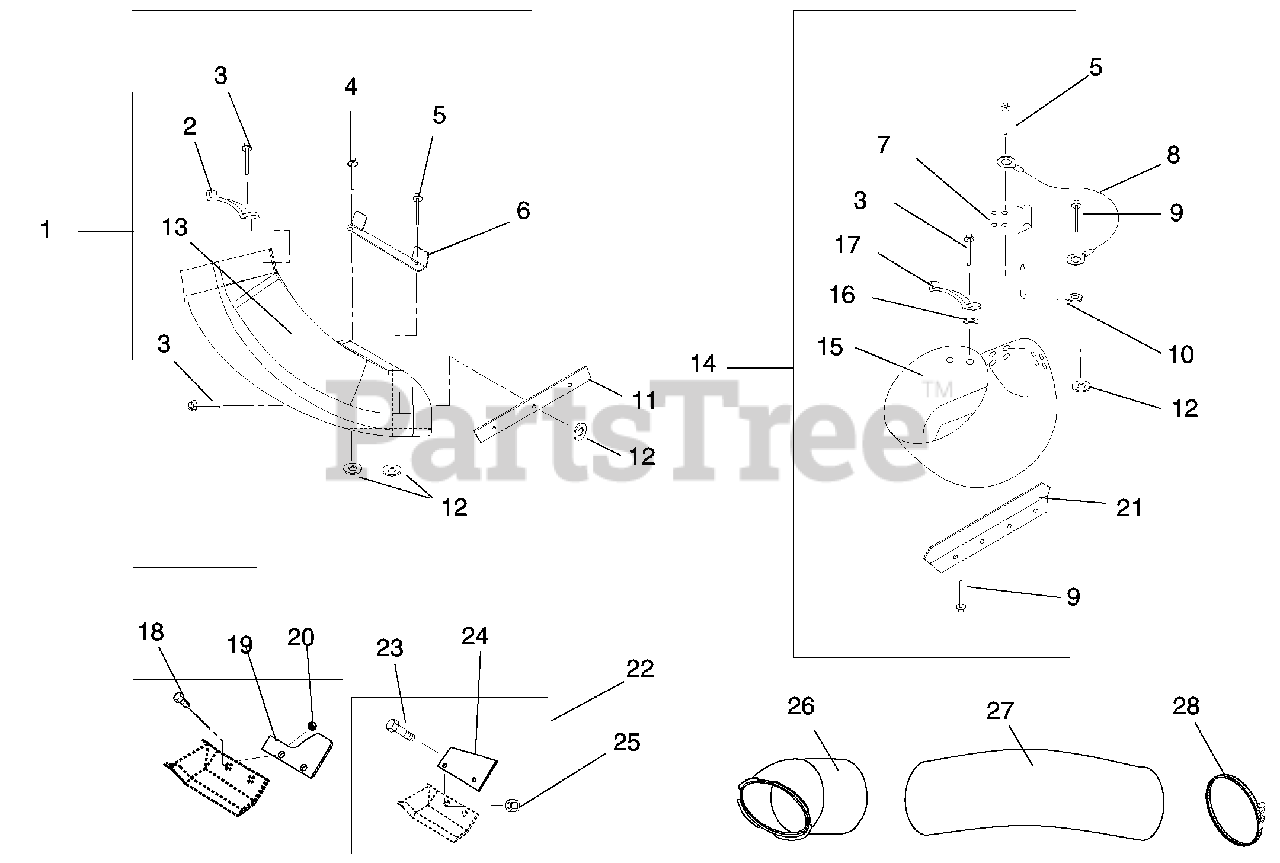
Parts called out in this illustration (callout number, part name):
1	BOOT, 28"&32" DECK BAGGER
2	TUBE RETAINER
3	RVT-POP.187X.527 DOME ST
4	RVT-POP.187X.277 DOME ST
5	RVT-POP .187X.402 DOME ST
6	BRKT, BAGGER BOOT MOUNT
7	BOOT BRACKET
8	LANYARD
9	RVT-TBLR .187X.375 ST-AL PL
10	PULL PIN
11	SKIRT, RUBBER
12	@WSHR-FL-STL.219X.50X.049 YWZC
13	28"/32" BOOT ASSY
14	MOWER BOOT ASSY- 40"
15	PAN BOOT ASSEMBLY
16	@WSHR-FL-STL.219X.50X.049 YWZC
17	TUBE RETAINER CLIP
18	BLT-HEX .31-24X.75 GR8 YWZC
20	NUT-CTRLK .31-24 YWZC
21	EXTENSION-CHUTE
22	SERVICE VANE PACKAGE
23	BLT-HEX .31-24X.75 GR8 YWZC
24	VANE
25	NUT-CTRLK .31-24 YWZC
26	BAGGER BOOT - UPPER
27	HOSE 7X38
28	CLAMP, 7" TOOL-LESS HOSE
